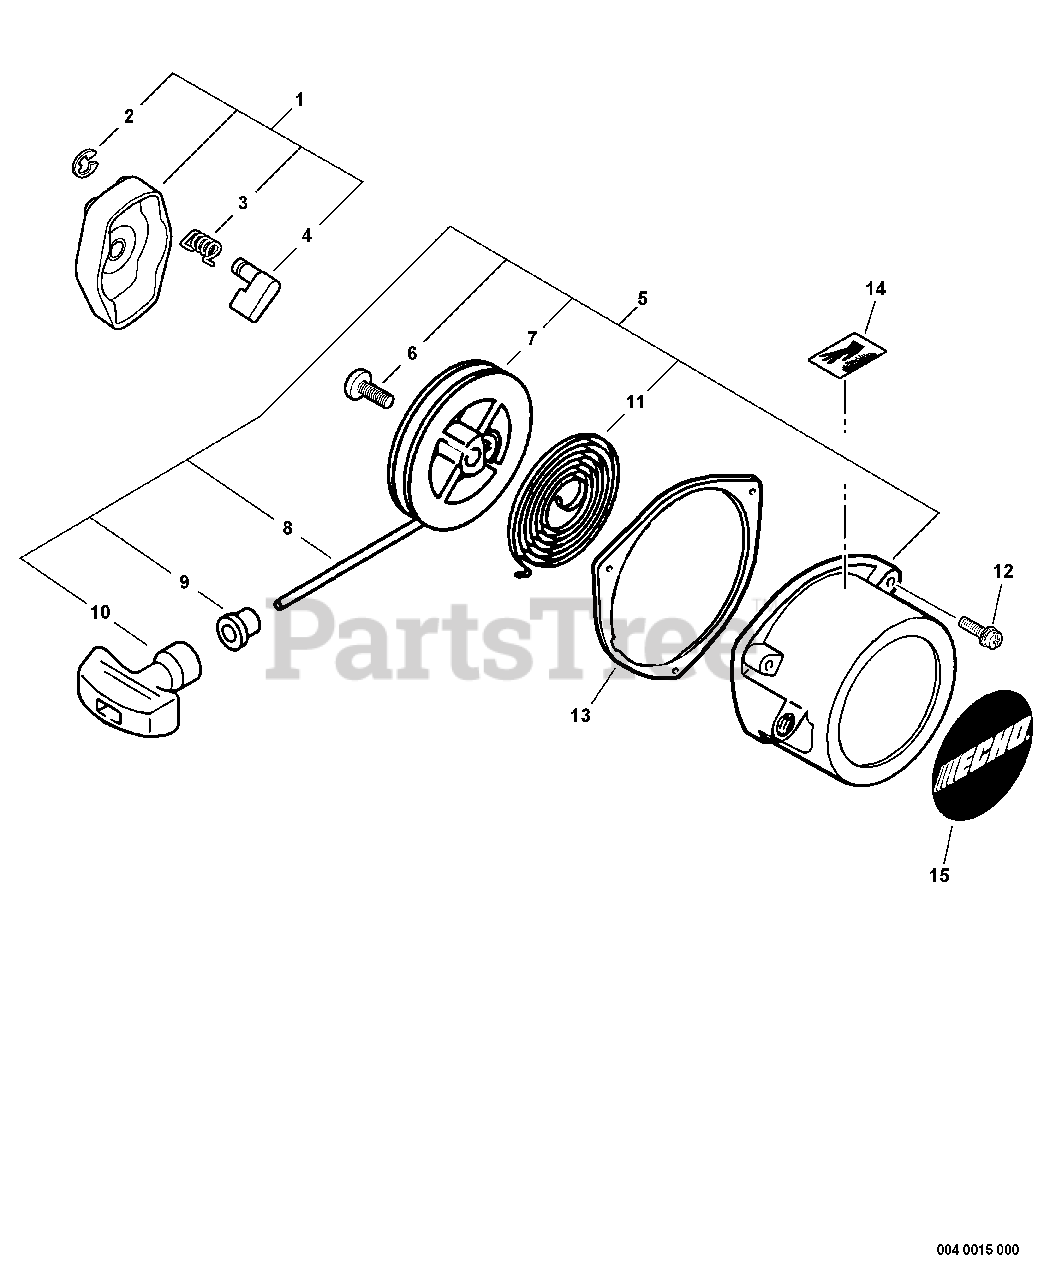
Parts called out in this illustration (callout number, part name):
1	STARTER PAWL ASSY
2	RING, RETAINING - 4
3	SPRING, RETURN
4	PAWL, STARTER
5	STARTER ASSY
7	REEL, ROPE
8	ROPE, STARTER - 4X880
9	GUIDE, ROPE
10	GRIP, STARTER
11	SPRING, REWIND
12	SCREW - 5X18
13	GASKET, STARTER
14	LABEL - HOT SURFACE
15	LABEL - ECHO
